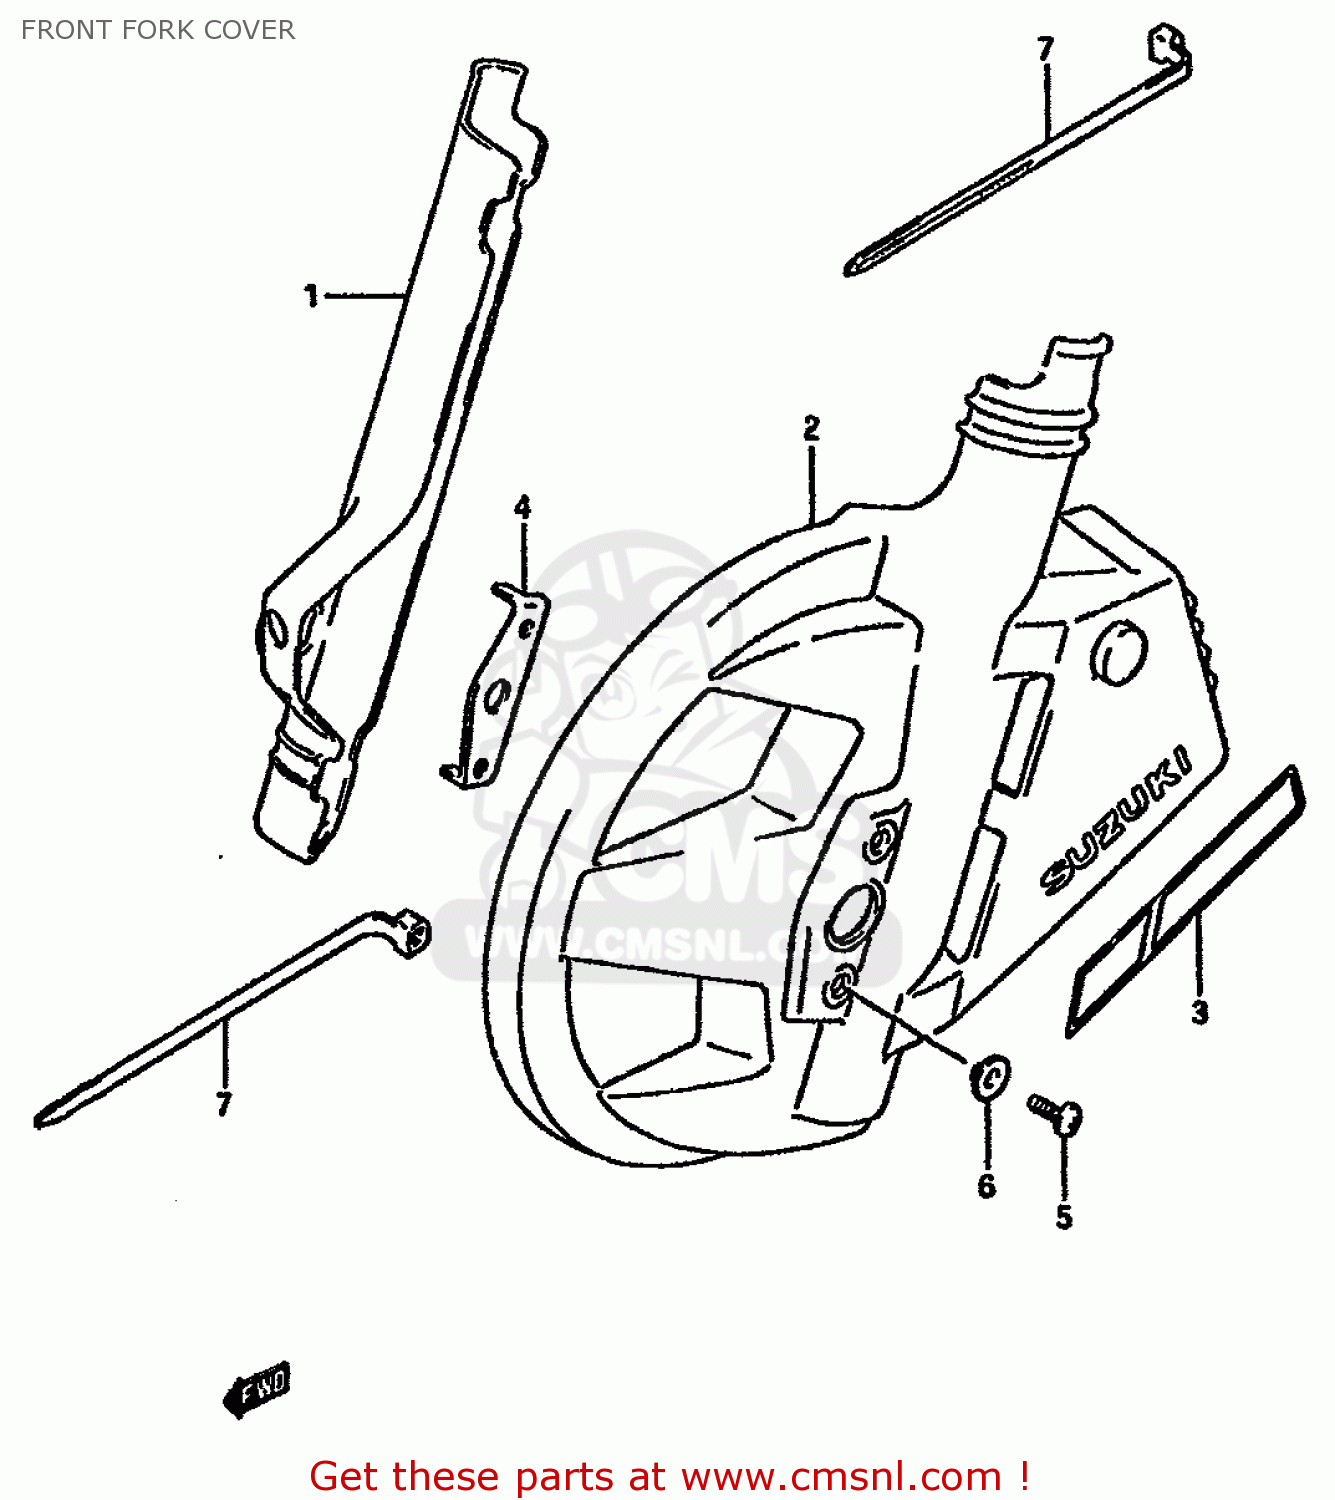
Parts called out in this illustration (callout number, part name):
1	PROTECTOR,FR FORK,R
2	PROTECTOR
3	TAPE,PROTECTOR LH
4	PLATE,PROTECTOR SET
5	SCREW 6X12
6	WASHER
7	CLAMP
